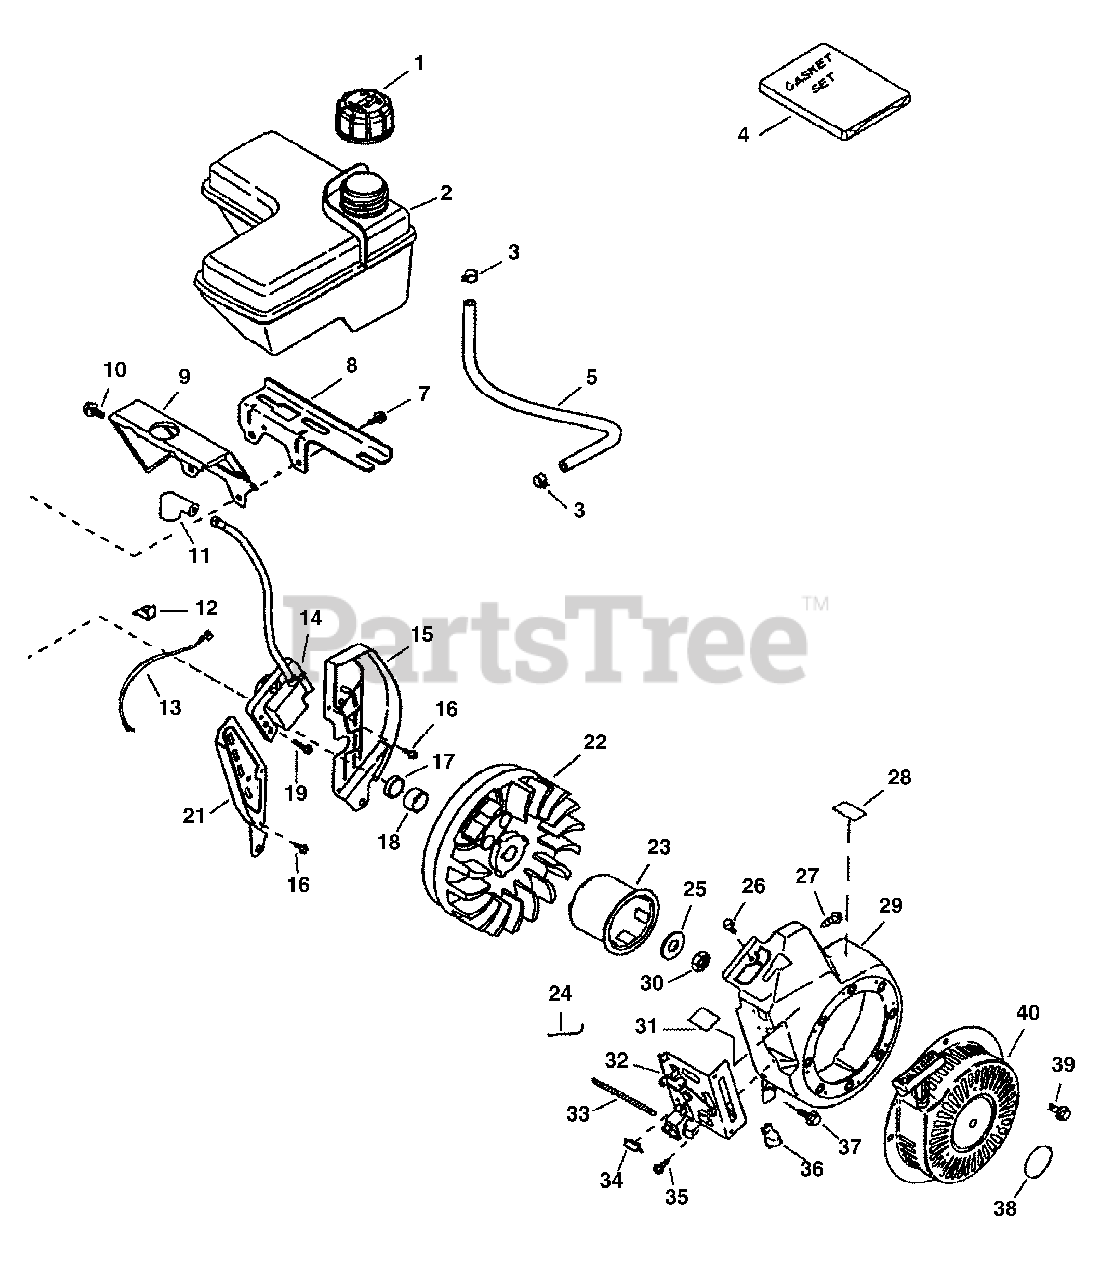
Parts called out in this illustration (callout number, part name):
1	Fuel Cap
2	Fuel Tank
3	Fuel Line Clamp
4	Gasket Set
5	Fuel Line
7	Screw, 1/4-20 x 7/8"
8	Fuel Tank Bracket
9	Blower Housing Extension
10	Screw, 10-24 x 9/16"
11	Spark Plug Cover
12	Wire Clip
13	Ground Wire
14	Solid State Ignition
15	Air Baffle (Right)
16	Screw, 10-24 x 9/16"
19	Screw, Torx T-15, 15/16"
21	Air Baffle (Left)
23	Starter Cup
24	Governor Link
25	Bell Washer
26	Screw, 1/4-20 x 31/64"
27	Screw, 10-32 x 1/2"
28	Lube Decal
29	Blower Housing
30	Flywheel Nut
31	Speed Control Decal
32	Control Bracket
33	Extension Spring
35	Screw, 10-32 x 1/2"
36	Control Knob
37	Screw, 1/4-20 x 31/64"
38	Starter Decal
39	Rivet
40	Rewind Starter
